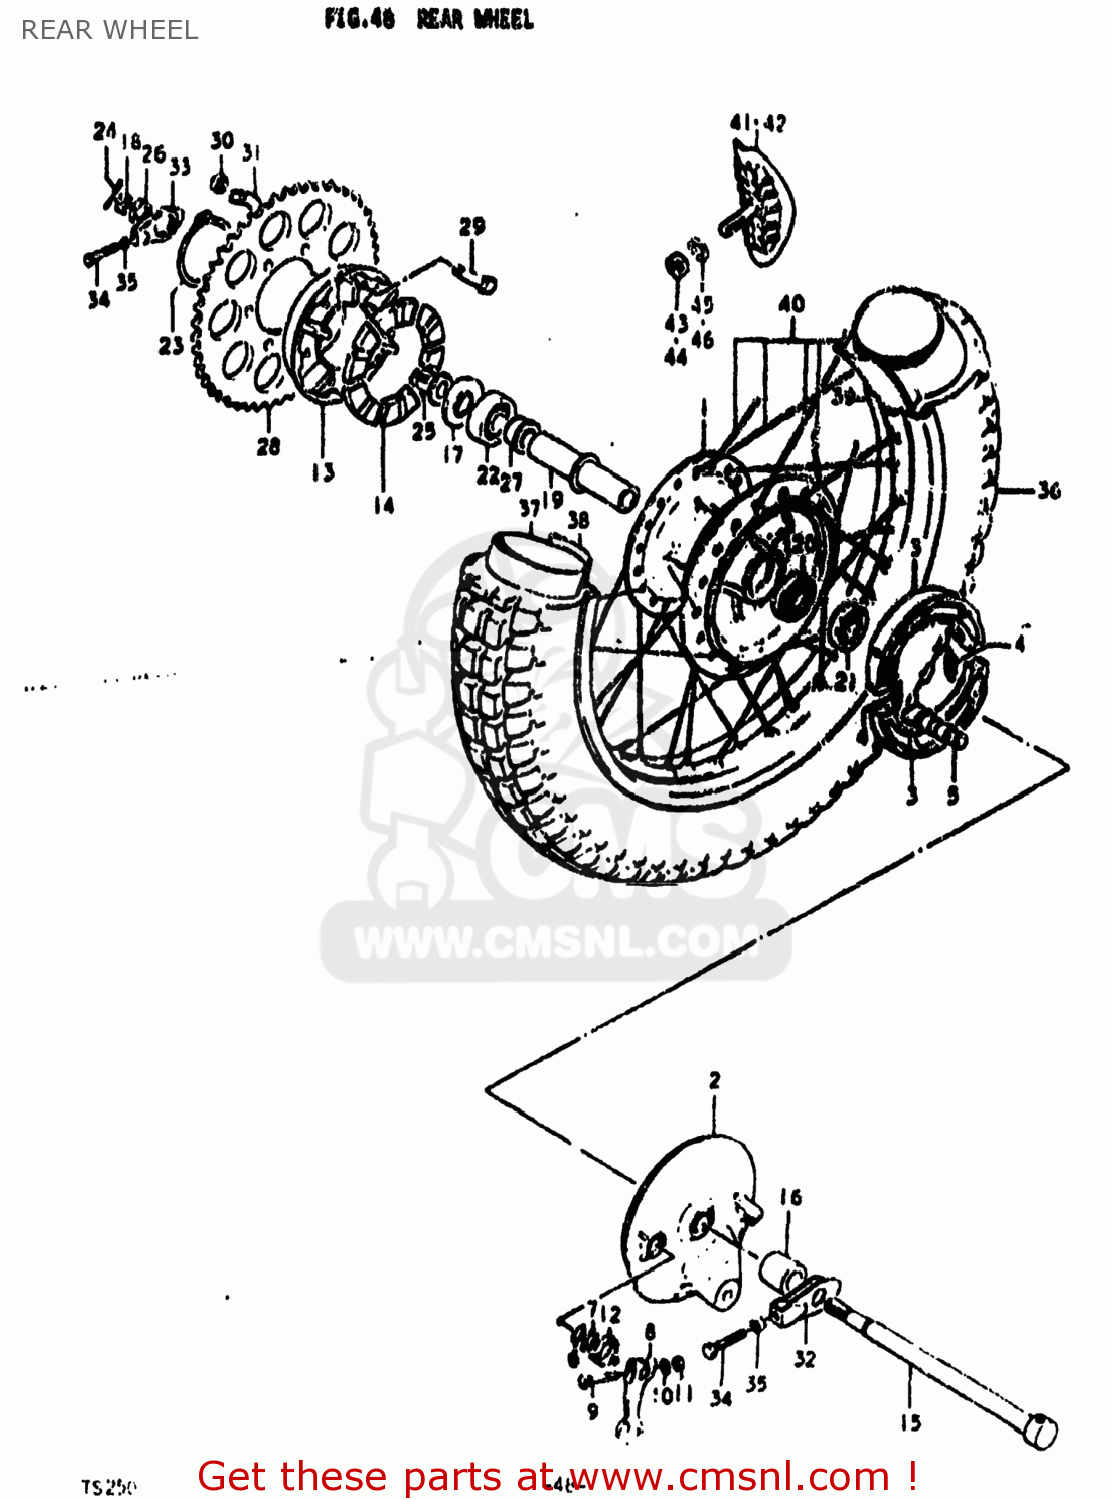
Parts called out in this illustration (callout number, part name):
1	HUB,REAR
2	PANEL,REAR HUB
3	SHOE,BRAKE
4	SPRING
5	CAM,FRONT BRAKE
6	O-RING,BOSS
7	WASHER (15X24X1.6)
8	LEVER,REAR BRAKE CAM
9	BOLT
10	WASHER
11	NUT
12	SPRING
13	DRUM,REAR SPROCKET MOUNT
14	CUSHION,REAR DRUM
15	AXLE,REAR
16	SPACER (15.2X26X20)
17	SPACER,REAR AXLE,RIGHT
18	NUT
19	SPACER,REAR HUB BEARING
20	BEARING, RH
21	OIL SEAL
22	BEARING
23	CIRCLIP
24	PIN 30X40
25	SPACER,REAR AXLE,LEFT
26	NUT
27	SPACER,REAR HUB BEARING
28	SPROCKET,REAR
29	BOLT(8X33.5)
30	NUT
31	WASHER
32	ADJUSTER,CHAIN
33	ADJUSTER,CHAIN
34	BOLT
35	NUT
36	TIRE
37	TUBE ASSEMBLY,WHEEL,INNER
38	PROTECTOR,WHEEL,INNER
39	RIM,REAR WHEEL
40	SPOKE SET,REAR
41	STOPPER,BEAD
42	STOPPER,BEAD
43	NUT
44	NUT
45	WASHER
46	WASHER
